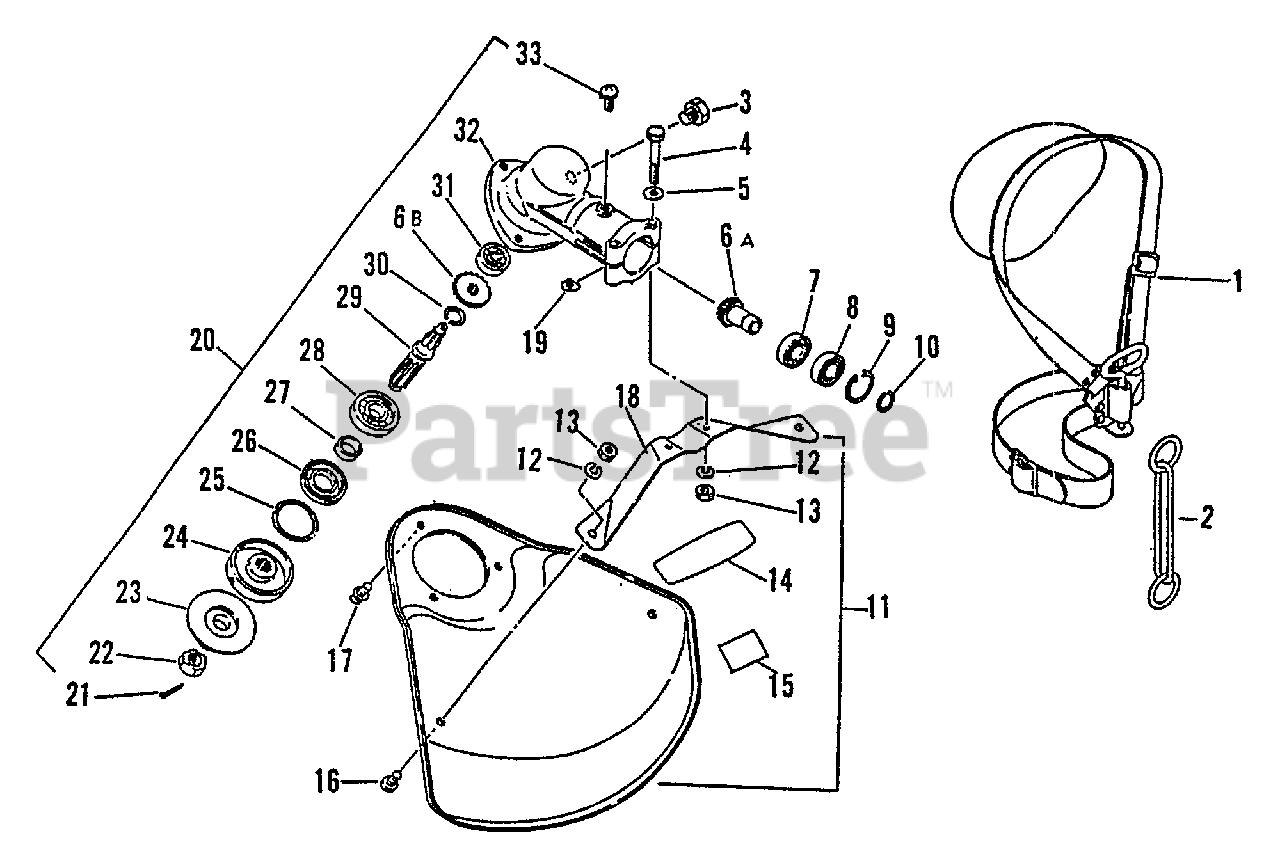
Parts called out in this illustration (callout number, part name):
1	SHOULDER STRAP ASSY
3	BOLT - 8X8
4	BOLT - 5X35
5	WASHER - 5
6	GEAR SET - BEVEL
7	BEARING, BALL - 6900
8	BEARING, BALL - 6900Z
9	RING, RETAINING - 22
10	RING, RETAINING - 12
11	DEBRIS SHIELD KIT
12	LOCKWASHER - 5
14	LABEL - LESCO
15	LABEL - CAUTION
16	SCREW - 5X8
17	SCREW - 5X10
18	BRACKET, SHIELD
20	GEAR CASE ASSY
21	PIN, SPLIT - 2X22
22	NUT - 10 -- LEFT HAND
23	ADAPTOR, BLADE - LOWER
24	ADAPTOR, BLADE - UPPER
25	RING, RETAINING - 32
26	SEAL, OIL
28	BEARING, BALL - 6201
29	GEAR - SHAFT
30	RING, RETAINING - 10
31	BEARING, BALL - 609
32	CASE, GEAR
33	SCREW - 5X10
